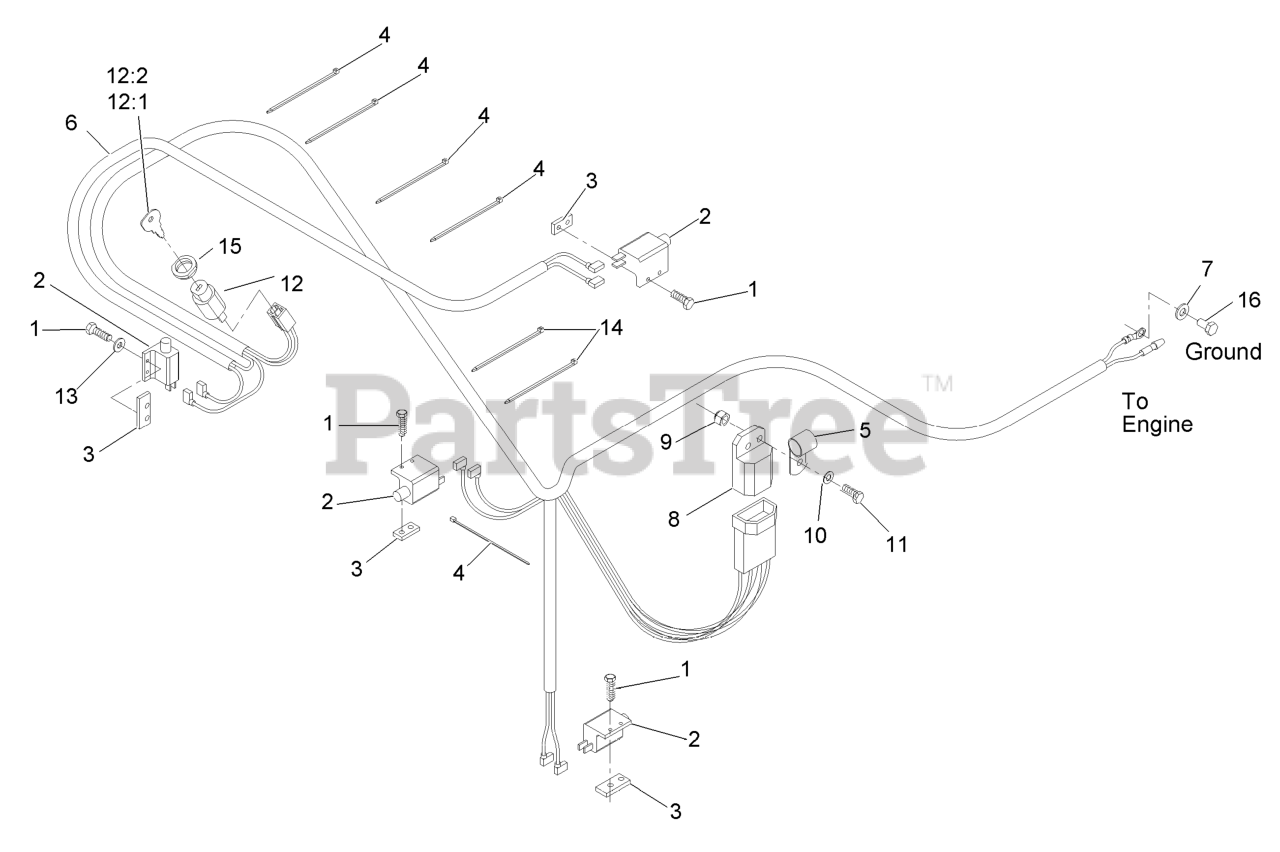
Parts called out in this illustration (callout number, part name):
1	SCREW-PPH
2	SWITCH-OPEN, NORMALLY
3	PLATE-TAPPED
4	TIE-CABLE
5	CLIP-LOOM
6	HARNESS,WIRING KA PULL ST
7	WASHER-PLAIN
8	MODULE-INTERLOCK
9	NUT-LOCK, NI
10	WASHER-FLAT
11	SCREW-HH
12	SWITCH & KEY (INCLUDES NU
12:1	KEYS-IGNITION (SPARE PAIR
12:2	KEY-IGNITION
13	WASHER-FLAT
14	TIE-PLASTIC
15	NUT-SWITCH, IGNITION
16	SCREW-HH
